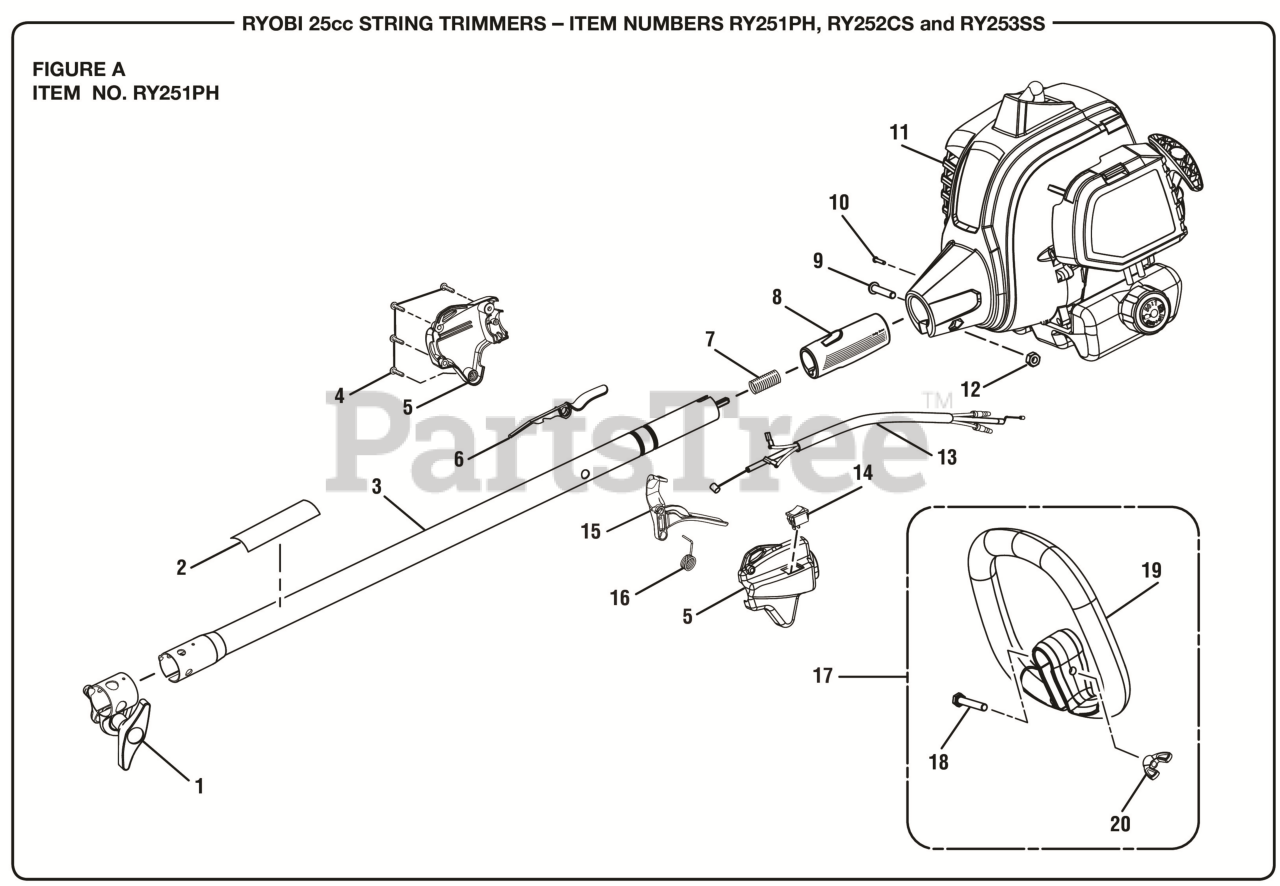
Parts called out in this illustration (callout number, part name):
1	Boom Clamp Assembly
2	Warning Icon Label
3	Upper Boom Assembly
4	Screw (M4 x 20 mm, T20 Torx Pan Hd. S.T.)
5	Control Handle Assembly (Inc. Key No. 6)
6	Trigger Lock
7	COMPRESSION SPRING
8	Rear Handle Grip
9	Screw (M6 x 30 mm, T27 Torx Button Hd.)
10	Screw (M4 x 8 mm, T25 Torx Pan Hd. T.F.)
11	Powerhead Assembly w/Labels
12	Hex Nut (M6.3 x 1)
13	Throttle Cable and Wire Assembly
14	Stop Switch (Momentary Contact)
15	Throttle Trigger
16	Torsion Spring (Throttle Trigger)
17	Auxiliary Handle Assembly
18	Screw (1/4-20 x 40 mm, Cap Hex Hd.)
19	Front Handle
20	Wing Nut (1/4-20, Plastic)
